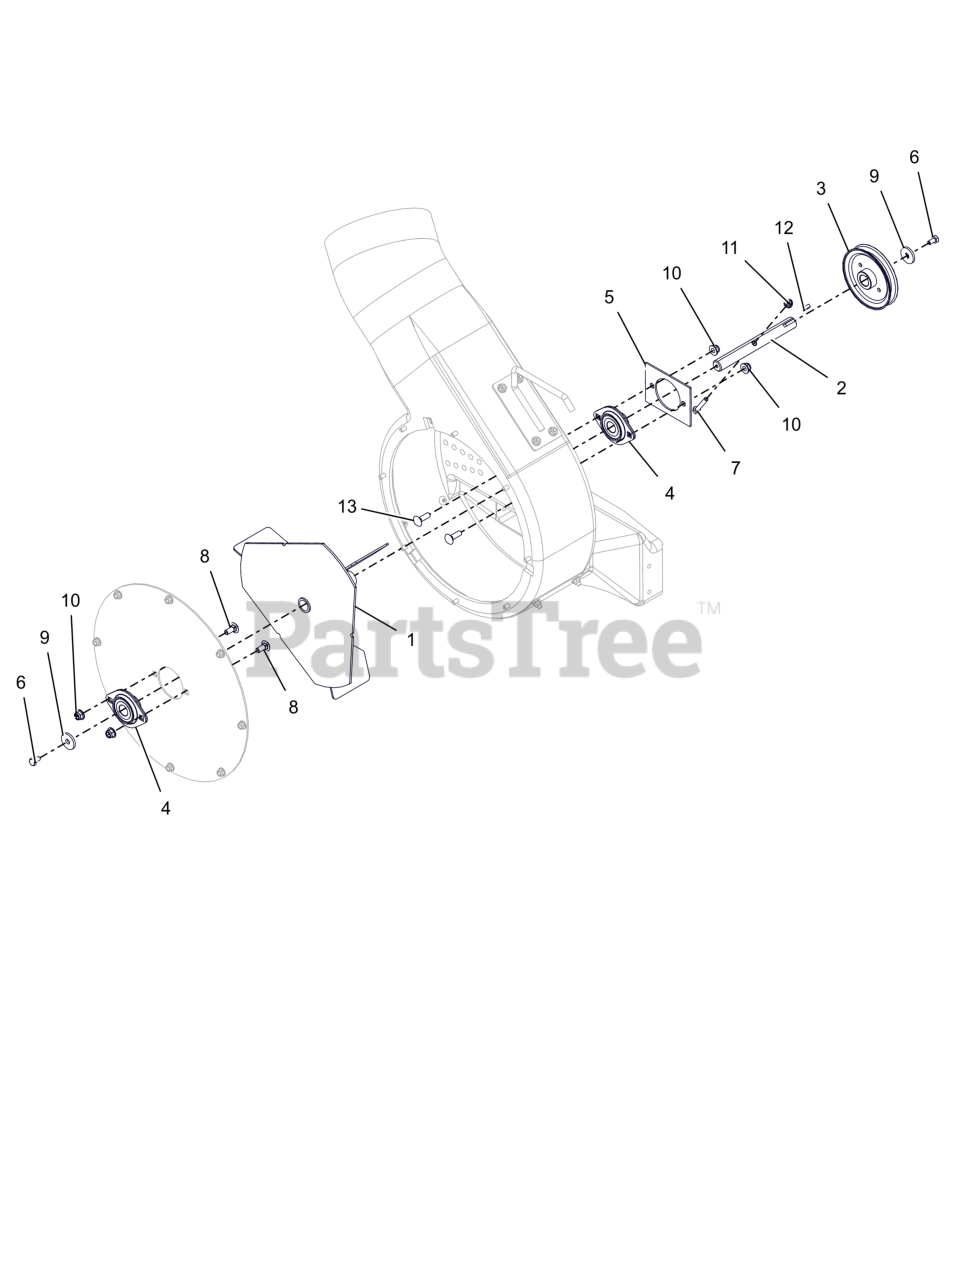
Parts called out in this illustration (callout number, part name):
1	WELDMENT, IMPELLER, 3 BLADE
2	SHAFT, IMPELLER
3	SHEAVE, BLOWER - 4.25 DIA.
4	BEARING, 2 BOLT FLANGE -.75 ID
5	BEARING WASHER PLATE - BLK
6	BLT, HEX .25-20X.50 G5ZCC EP80
7	BLT, HEX .25-20X1.50 G8 ZCC
8	BLT,RHSN .31-18X.75 G5 ZCC
9	WSHR, FLT .340X1.125X.135 ZCC
10	NUT,LK-NYL-FLG .31-18 G5ZC120
11	NUT,NYL-FLG .25-20 GF ZCC
12	KEY-SQ .187 X .50 X .187
13	BLT,RHSN .31-18X1.00 G5 ZCC
